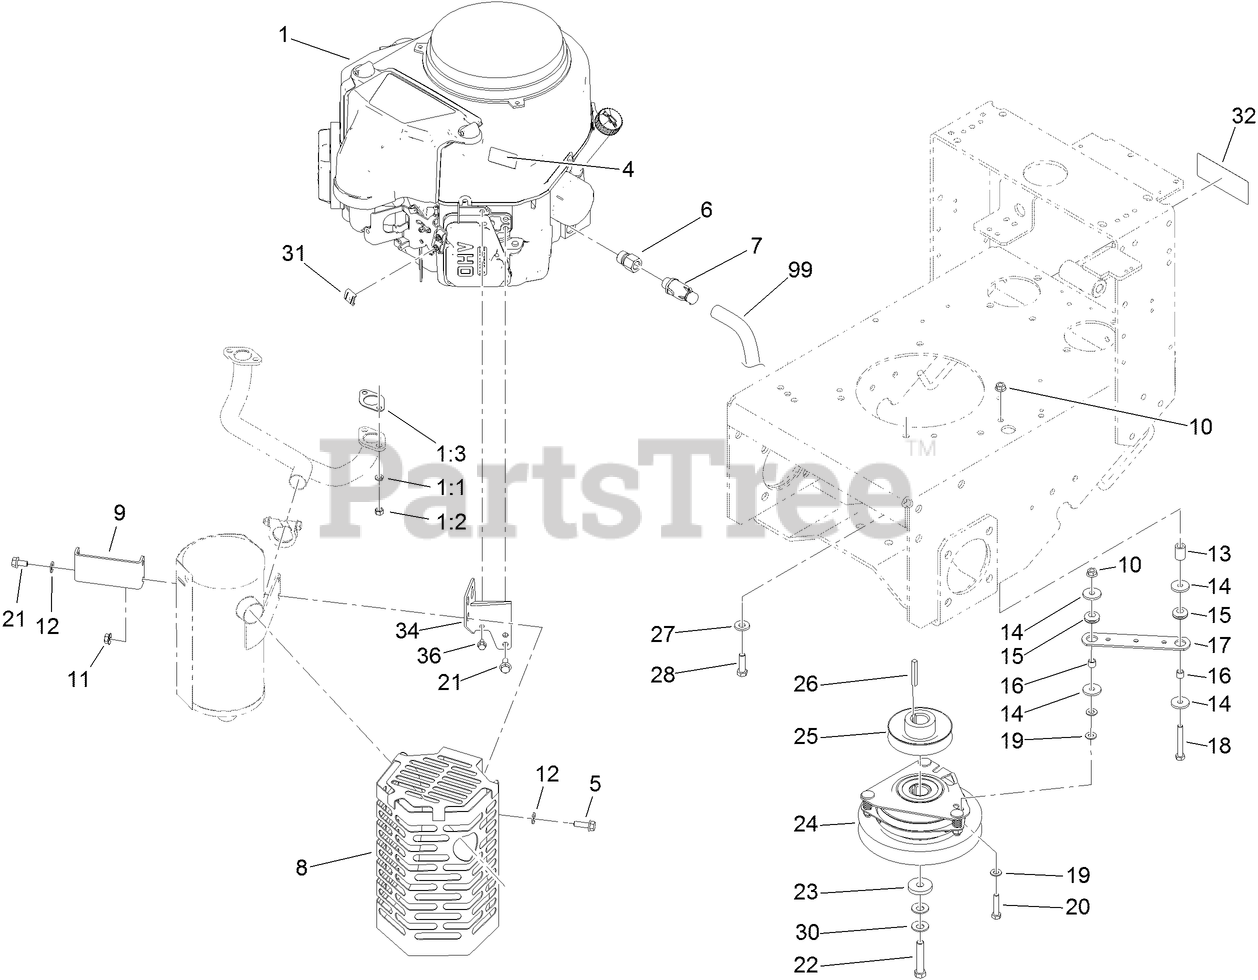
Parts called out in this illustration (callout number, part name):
1:1	WASHER-LOCK
1:3	GASKET-EXHAUST
4	DECAL-WARNING
5	SCREW-HHF
6	Adapter
7	VALVE-DRAIN, OIL
8	SHIELD-MUFFLER
9	BRACKET-SHIELD, MUFFLER
10	NUT-HF
11	NUT-HF, LOCK
12	WASHER-SPRING
13	TUBE-RETAINER
14	WASHER
15	GROMMET
16	SPACER
17	STRAP-CLUTCH, BRAKE
18	SCREW-HH
19	WASHER-PLAIN
20	SCREW-HH
21	SCREW-HHF
22	SCREW-HH
23	WASHER
24	CLUTCH / BRAKE ASM
25	Pulley
26	KEY-SQUARE
27	WASHER-BELLEVILLE
28	SCREW-HH
30	WASHER-SPRING
31	CLAMP-CABLE
32	DECAL-CAUTION
34	BRACKET-MUFFLER
36	SCREW-HHF
99	HOSE-DRAIN, OIL
